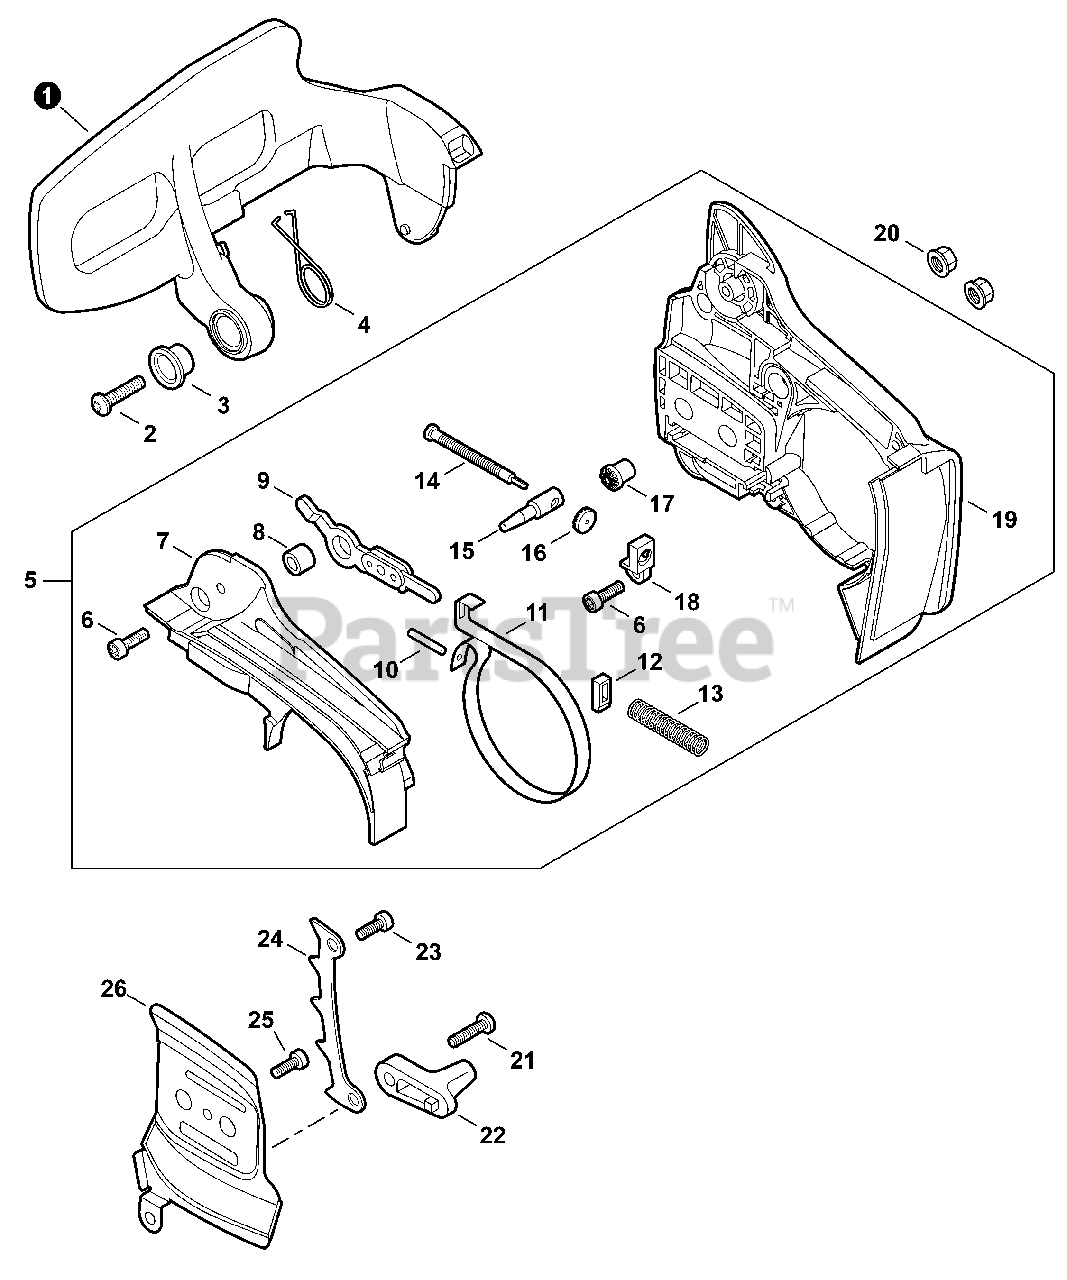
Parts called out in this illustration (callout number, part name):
1	LEVER, BRAKE
2	BOLT, TORX 5×12
3	COLLAR 10
4	SPRING, TORSION
5	BRAKE ASSY, CHAIN
6	BOLT, TORX 4×12
7	COVER, BRAKE
8	SPACER 8×12×9
9	CONNECTOR, BRAKE
10	PIN, SPRING 3x-9.8
11	BAND, BRAKE
13	SPRING, COMPRESSION
15	TENSIONER, CHAIN
16	GEAR, BEVEL
17	GEAR, BEVEL
18	COLLAR 8
19	GUARD, SPROCKET
20	NUT, FLANGE M8×1.25
21	BOLT, TORX 5×20
22	CHAIN CATCHER
23	BOLT, TORX 5×20
24	SPIKE, BUMPER
25	BOLT, TORX 4×12
26	PLATE, GUIDE - INNER
